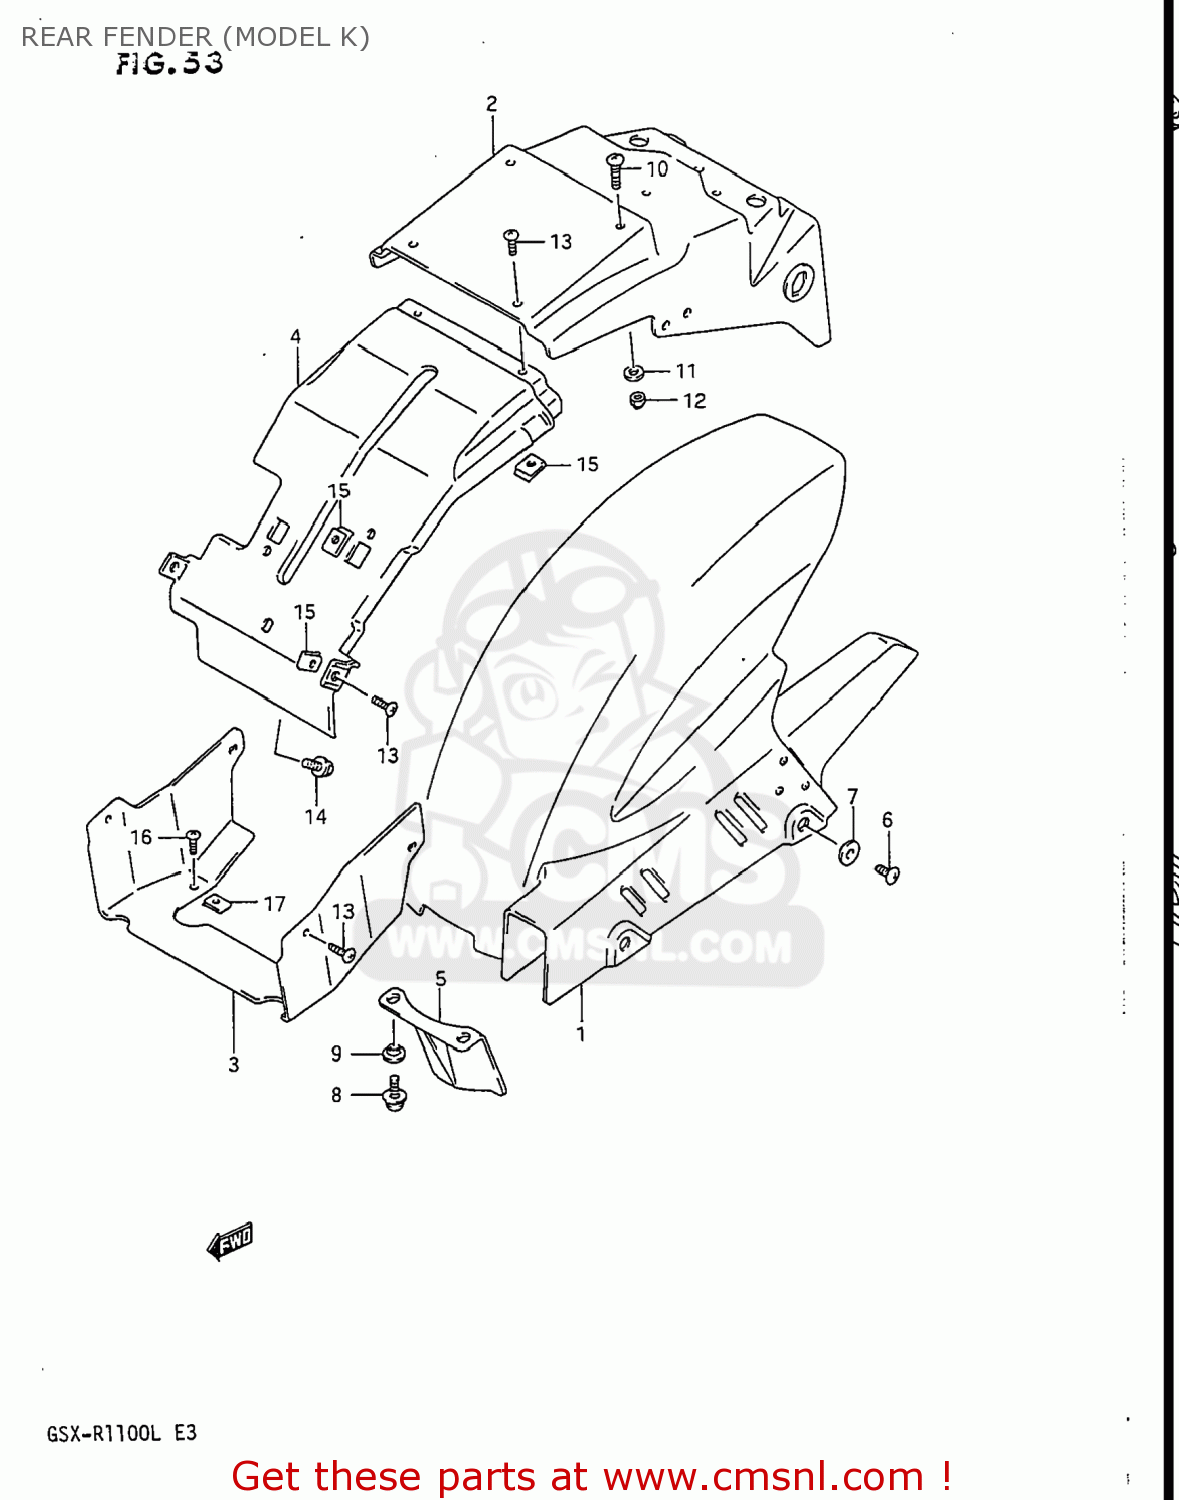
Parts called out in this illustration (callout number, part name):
1	FENDER,RR LWR
2	FENDER,REAR
3	FENDER,REAR
4	FENDER,RR UPR FR NO.2
5	GUARD,RR UNIT MUD
6	SCREW
7	WASHER
8	SCREW(6X16)
9	WASHER,LOCK
10	SCREW
11	WASHER
12	NUT 6MM
13	SCREW, FRONT & REAR
14	BOLT
15	NUT,HEADLAMP HOUSING,UPPER
16	SCREW, FRONT & REAR
17	NUT,HEADLAMP HOUSING,UPPER
